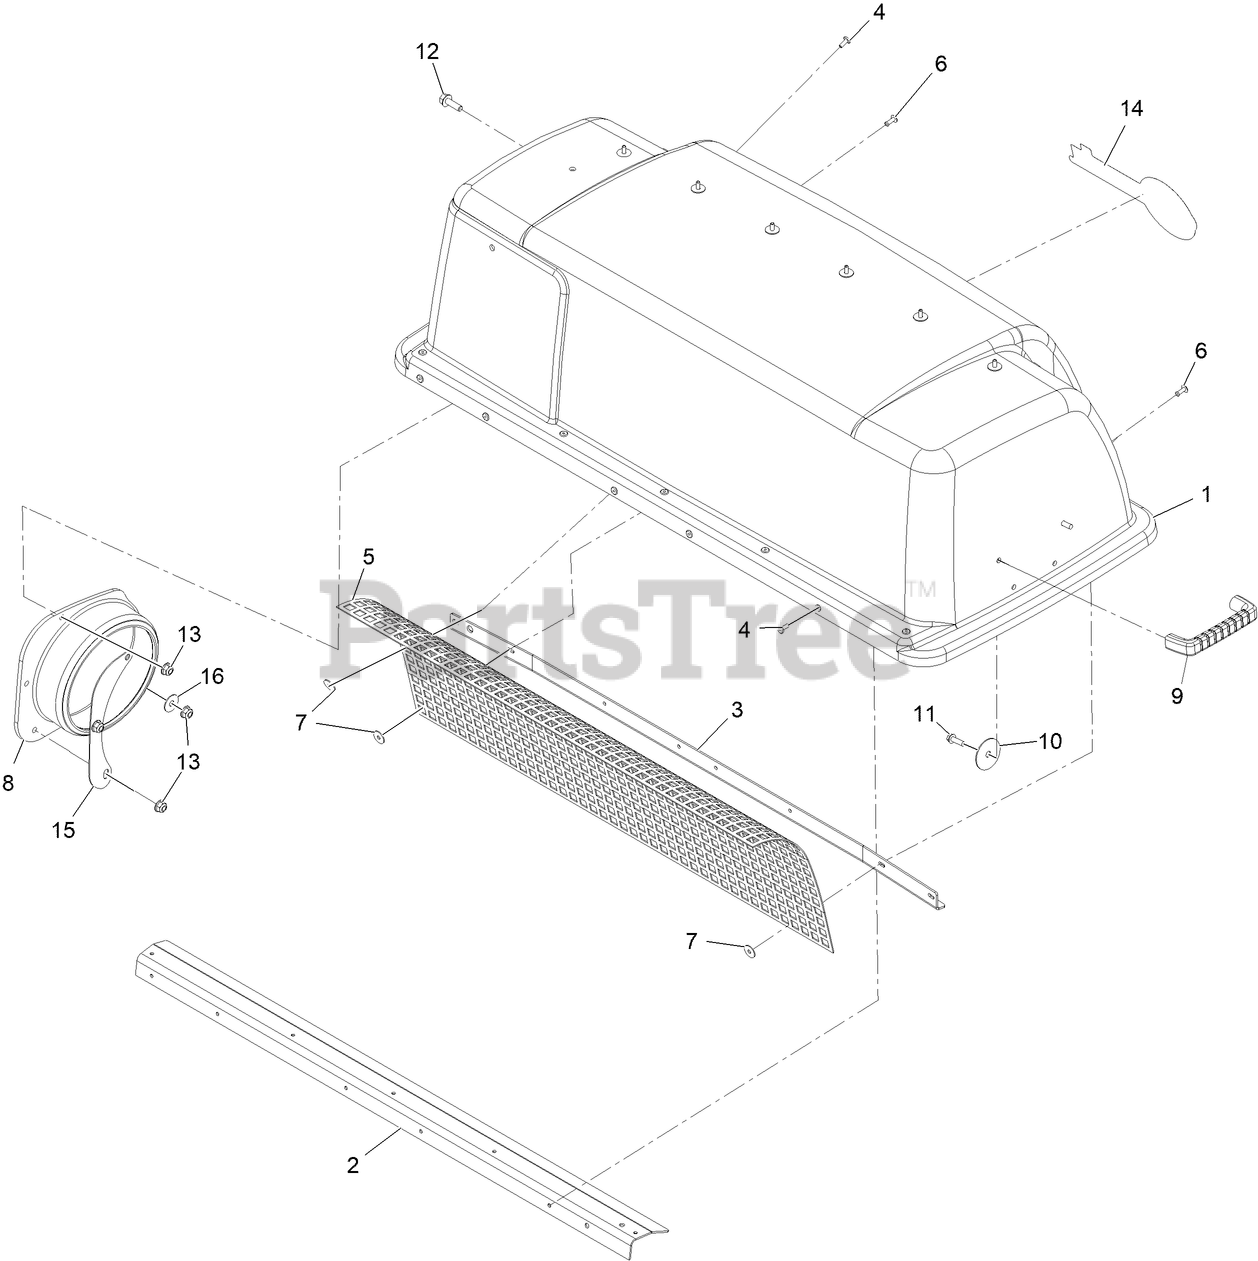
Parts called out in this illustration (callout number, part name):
1	HOOD-BAGGER
2	STIFFENER-BAGGER, TOP
3	X-REF TO 138-5849-03
4	RIVET-BLIND
5	SCREEN-BAGGER
6	RIVET-POP
7	WASHER-FLAT
8	ADAPTER-INLET, HOOD
9	HANDLE-DOOR
11	SCREW-HWH
12	SCREW-HHF
13	NUT-HF, NI
14	DECAL-EXMARK LOGO
15	Plate-Hood Inlet Support
